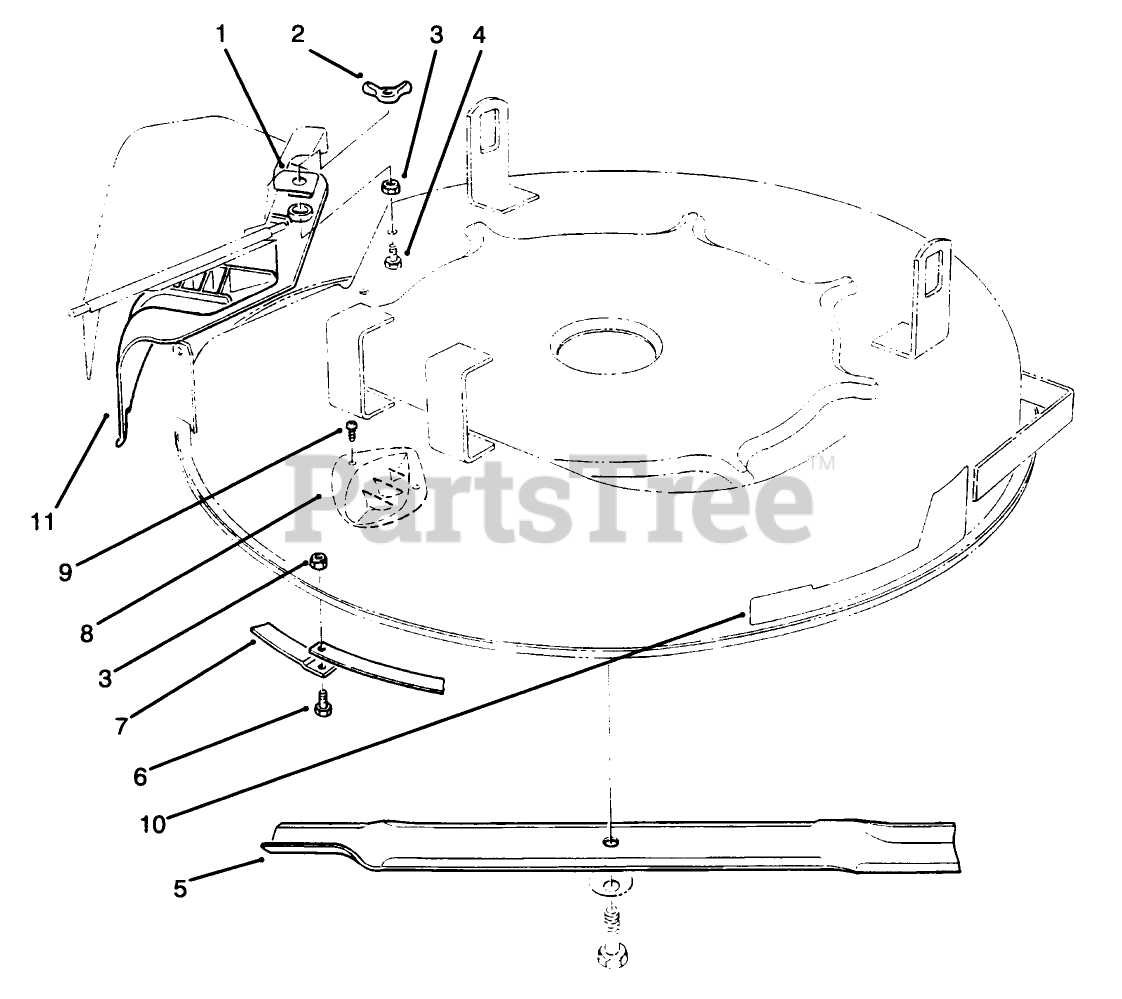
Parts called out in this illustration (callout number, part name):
2	NUT-WING SPECL
3	NUT-LOCK, NI
4	SCREW-HHF
6	SCREW-HH
8	KICKER
9	#8 X .625" PHILPS PAN H
11	COVER- 25" (W/KICKER)
